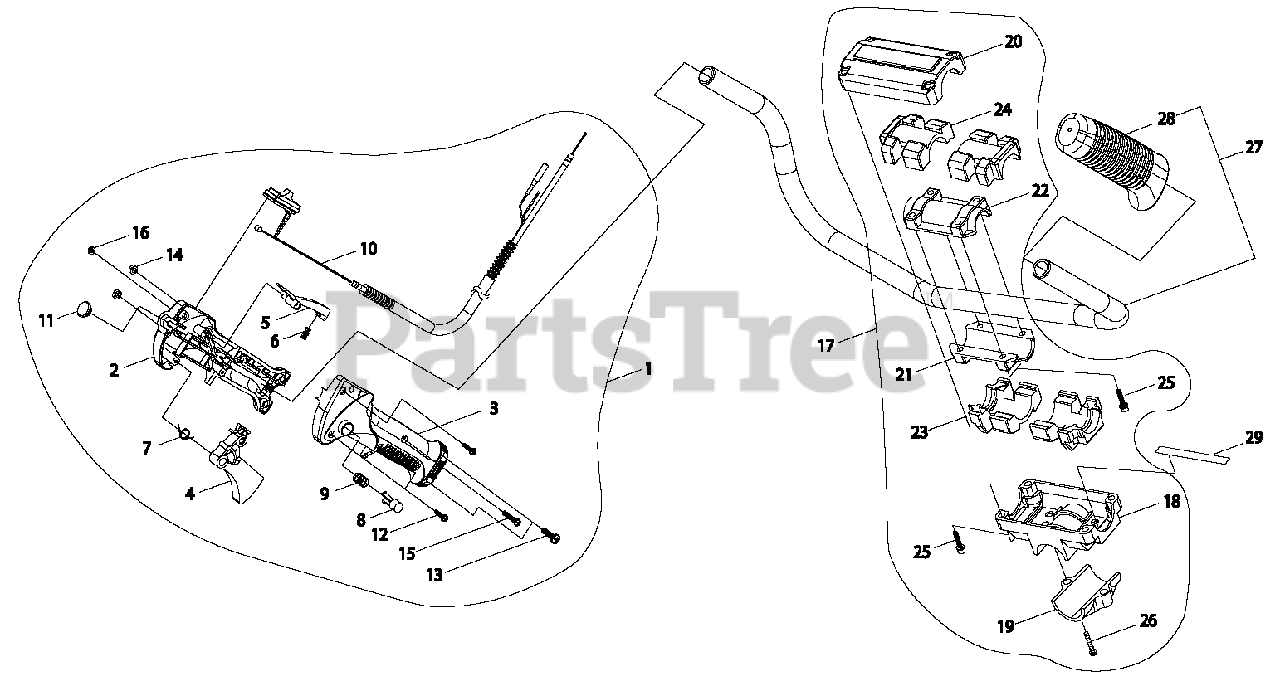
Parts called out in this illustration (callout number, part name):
1	CONTROL HANDLE ASSY
2	HANDLE, CONTROL - RIGHT
3	HANDLE, CONTROL - LEFT
4	TRIGGER, THROTTLE
5	LEVER, TRIGGER LOCKOUT
6	SPRING
7	SPRING, TRIGGER
8	LOCK, THROTTLE
9	SPRING
10	CONTROL CABLE ASSY
11	PLUG
12	SCREW - 4X16 -- TAPPING
13	SCREW - 5X20
14	NUT - 5
15	SCREW - 4X23
16	NUT - 4
17	HANDLE BRACKET KIT
18	BRACKET, HANDLE - LOWER
19	BRACKET, MOUNTING
20	BRACKET, HANDLE - UPPER
21	CLAMP - LOWER
22	CLAMP - UPPER
23	CUSHION - LOWER
24	CUSHION - UPPER
25	SCREW - 5X25
26	SCREW - 6X25
27	HANDLE ASSY
28	GRIP
29	LEAD - GROUND
